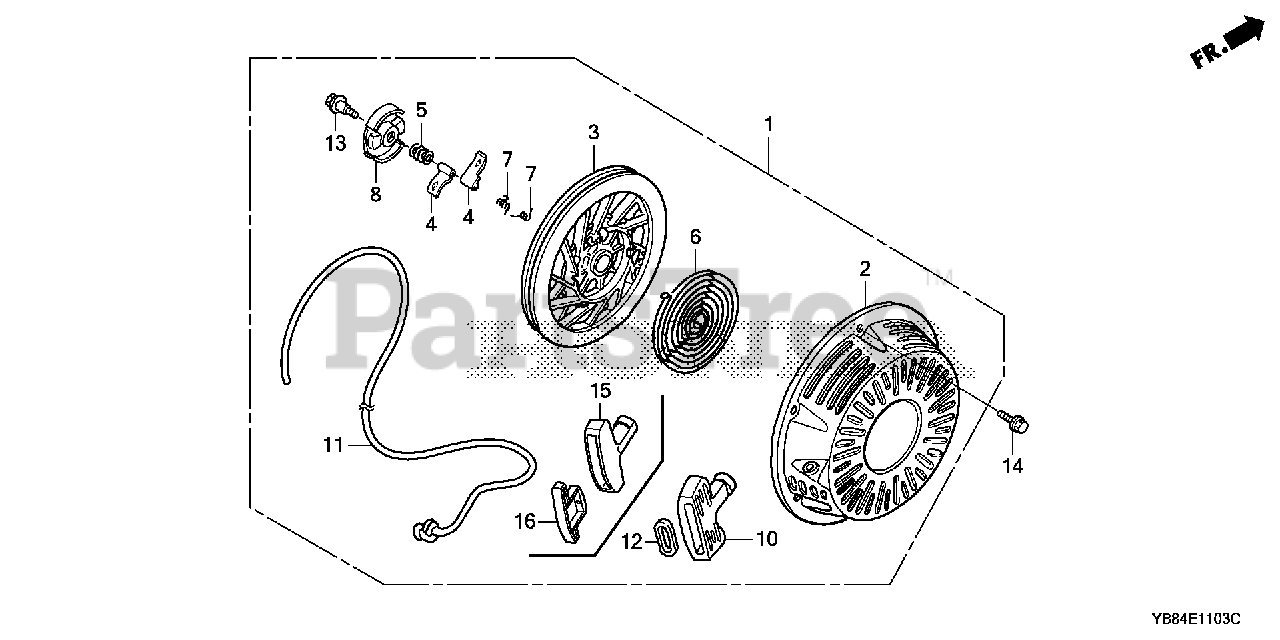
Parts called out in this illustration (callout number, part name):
1	STARTER ASSY., RECOIL *R280* (POWER RED)
2	CASE, RECOIL STARTER *R8* (BRIGHT RED)
2	CASE, RECOIL STARTER *R280* (POWER RED)
3	PULLEY, RECOIL STARTER
4	RATCHET, STARTER
5	SPRING, FRICTION
6	SPRING, STARTER RETURN
7	SPRING, RATCHET
8	RETAINER, SPRING
10	GRIP, STARTER
11	ROPE, RECOIL STARTER
12	REINFORCEMENT, GRIP
13	SCREW, CENTER
14	BOLT, FLANGE (6X10)
